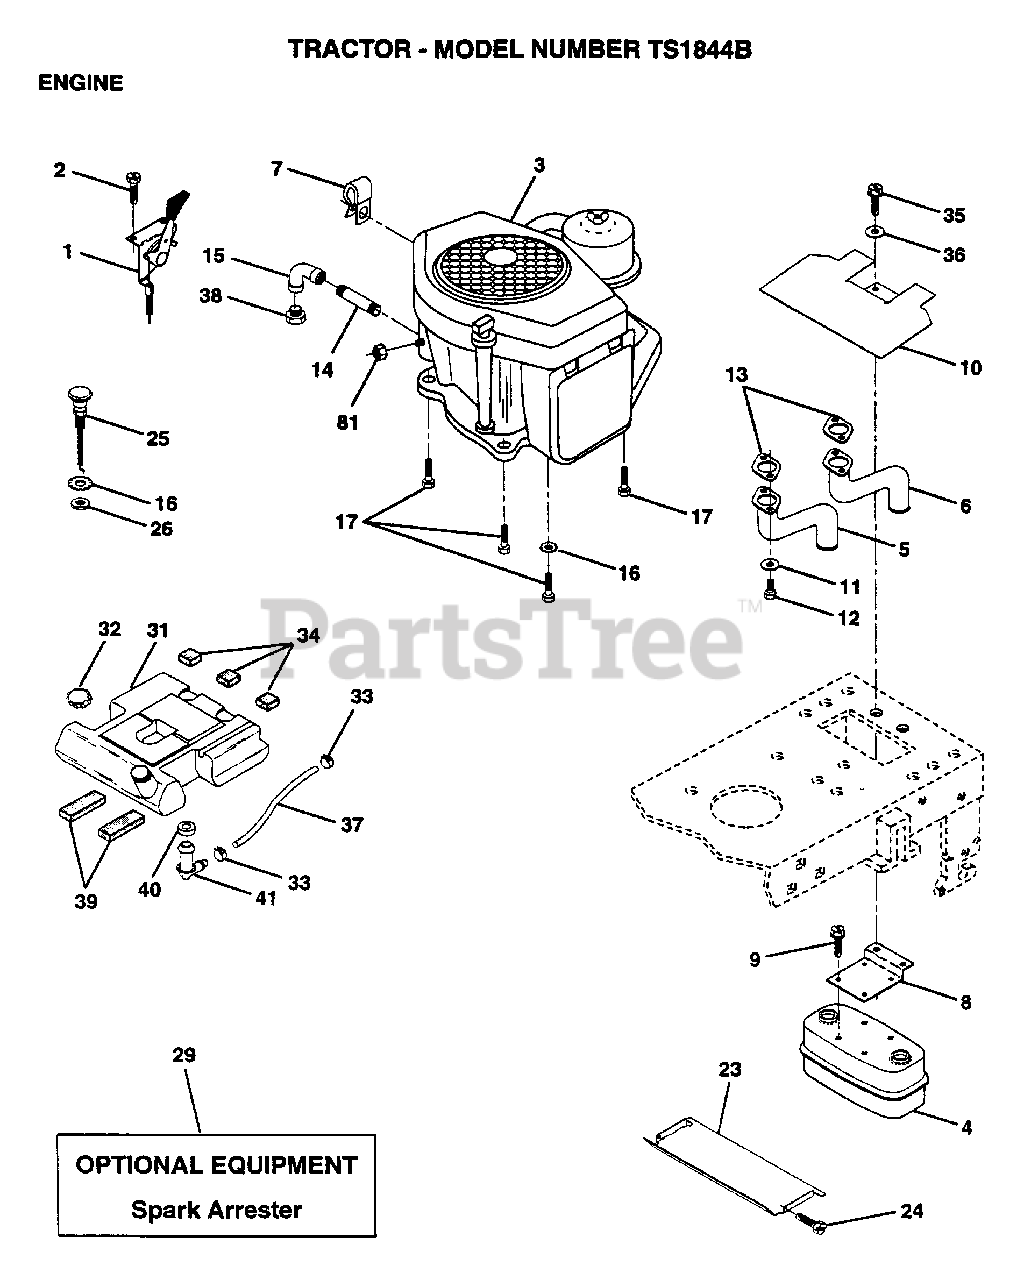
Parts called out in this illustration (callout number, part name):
2	SCREW LT
3	ENGINE, KOHLER
5	PIPE-EXHAUST.LH
6	PIPE-EXHAUST.RH.
7	CLIP T
8	BRACKET MUFFLER
9	SCREW ST
10	SHIELD.HEAT.MUFF.
11	LOCKWASHER
12	SCREW
14	PIPE NIPPLE LT
15	ELBOW
16	LOCKWASHER
17	SCREW LT
23	HEAT SHIELD
24	SCREW
32	CAP ASM FUEL
33	HOSE CLAMP
34	PAD-SPACER LT
35	SCREW
36	WASHER
37	FUEL LINE T
39	PAD IDLER TI
40	BUSHING OUTLET T
41	STEM.TANK.FUEL
81	NUT
